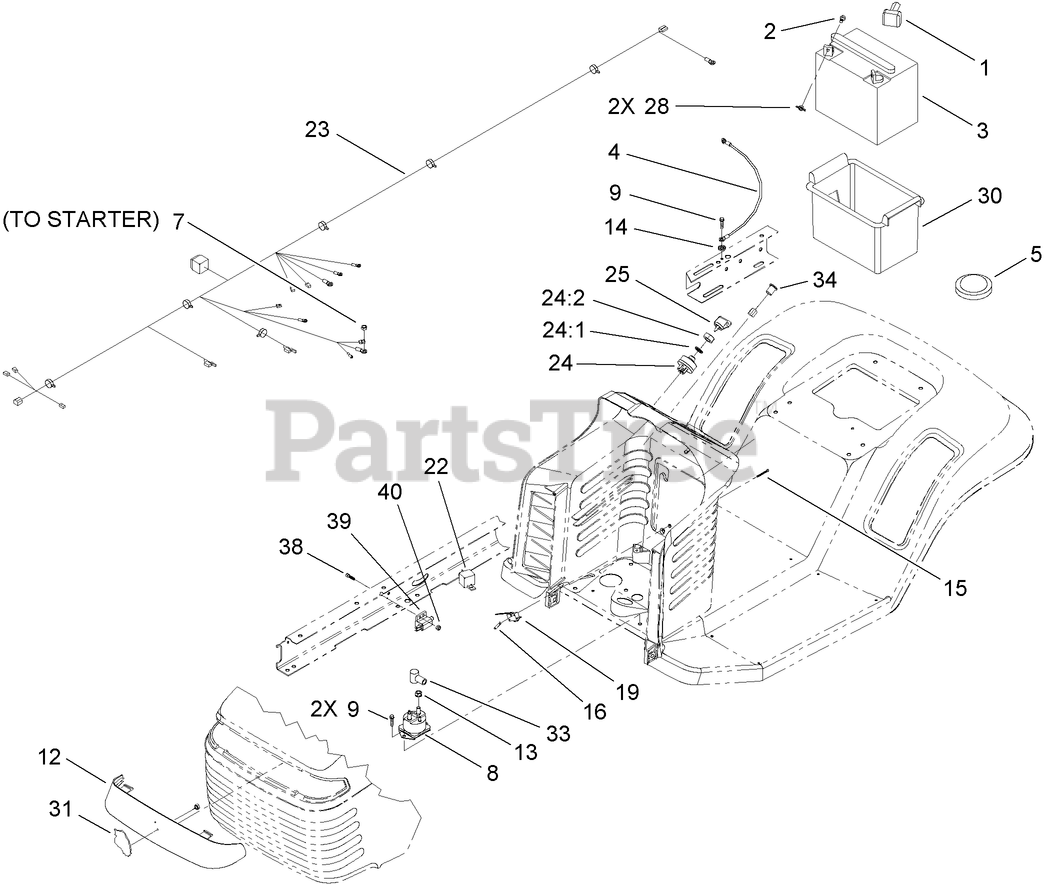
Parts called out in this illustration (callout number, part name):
1	BOOT-TERMINAL
2	SCREW-HH
4	WIRE ASM
5	SWITCH-SEAT
7	NUT-KEPS
8	SOLENOID-STARTER
9	SCREW-HWH
12	LENS-HEADLIGHT
13	NUT-KEPS
14	WASHER-LOCK/EXT
15	SCREW-HH
16	NUT-SPEED
19	SWITCH-MICRO
22	RELAY
23	HARNESS-WIRE
24:1	WASHER-LOCK
24:2	NUT-HH
25	KEY-IGNITION
28	NUT-WING
30	BOX-BATTERY
31	EMBLEM
33	BOOT-INSULATOR, TERMINAL
34	LIGHT-INDICATOR
38	SCREW-HSH
40	NUT-LOCK, NI
